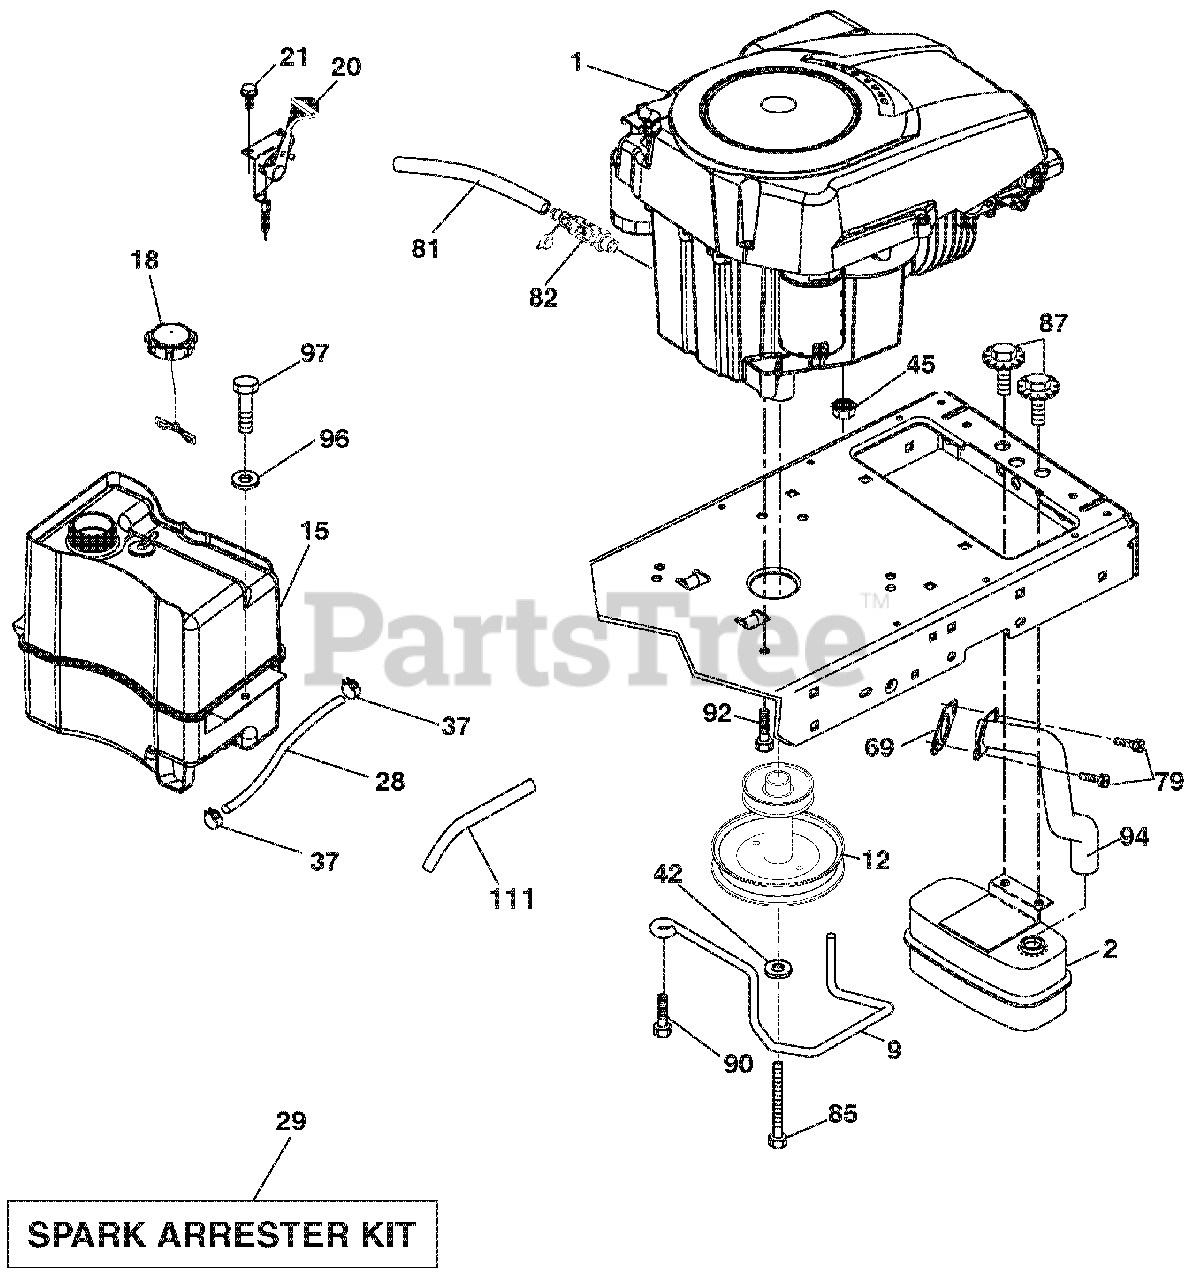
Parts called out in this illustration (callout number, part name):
1	ENGINE KOHL MODEL NO. SV601-3241 (585954701)(ORDER PARTS FROM ENGINE MANUFACTURER.)
2	MUFFLER
9	KEEPER BELT ENGINE
12	PULLEY.ENGINE.5.0.P.D.
15	TANK.FUEL.2.5.GAL.
18	CAP.FUEL
20	CONTROL THROTTLE/CHOKE
28	LINE.FUEL.20"
29	KIT.SPARK ARRESTOR(392390 B&S)
37	CLAMP.HOSE.BLK.
42	WASHER.LOCK.HVY HLCL.SPR.7/16
45	Nut, Keps Hex 1/4-20 unc
69	GASKET.KOHLER.SV.I.
79	SCREW SOCKET HEAD 5/16-18 X 1
81	TUBE.DRAIN.OIL.EASY
82	VALVE OIL DRAIN
85	BOLT.HEX.7/16-20X4XGR5-1.5THR.
87	BOLT.5/16-18 UNC X 1 W/SEMS.BL
90	SCREW.3/8-16X1.SMGML.TAP/R.BLK
92	SCREW.3/8-16 X 1.SMGML.TAP/R
94	TUBE.EXHAUST (ENGINE)
96	WASHER.9/32 X 7/8 X 16GA.
97	SCREW.HEXWSH.THDROL.1/4-20X3/4
111	PURGE.LINE.CARB
